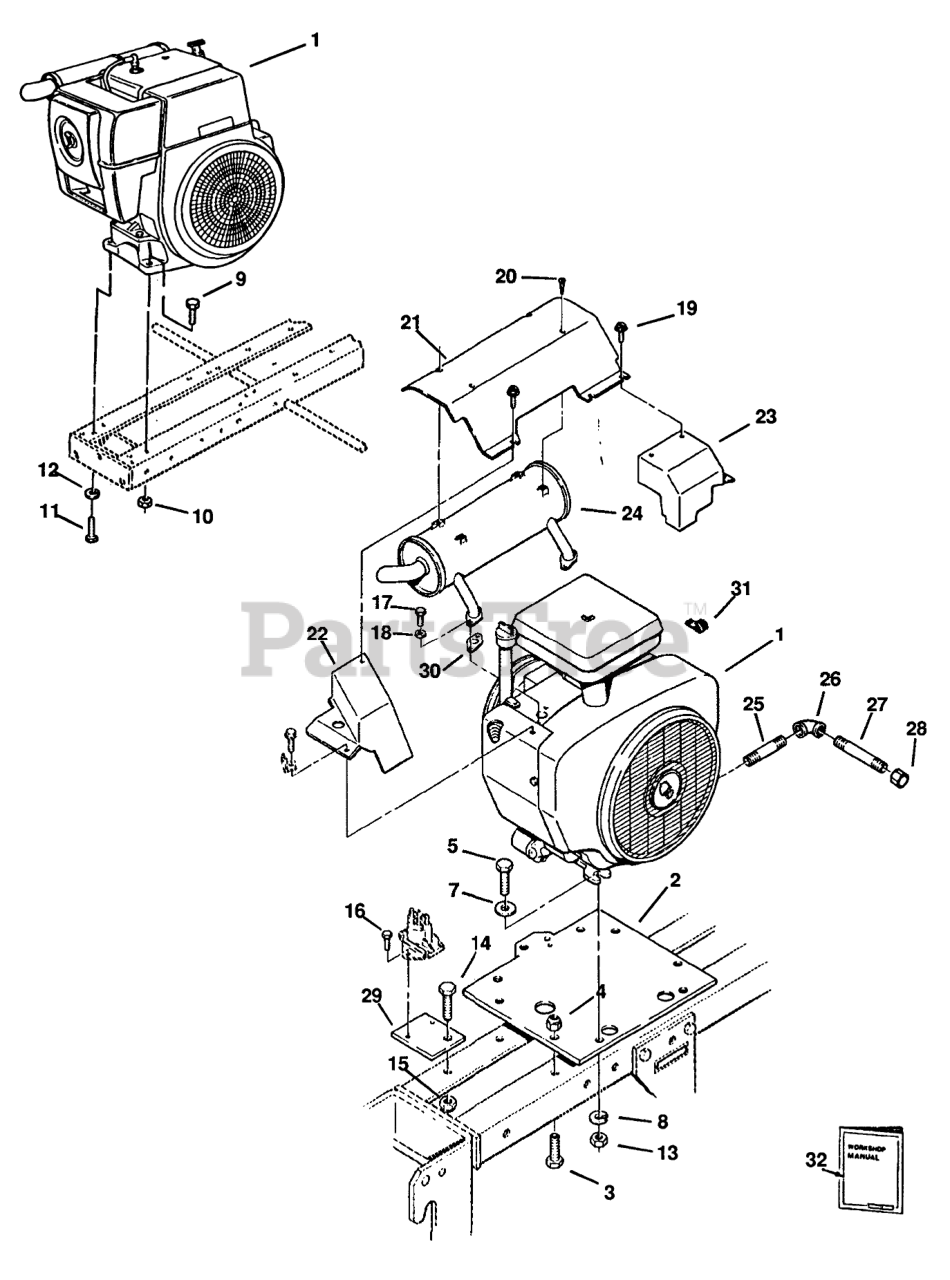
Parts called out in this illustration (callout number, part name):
1	Engine 10HP Kohler M-10-S Spec 461521310
1	Engine 12HP Kohler M-12-S Spec 471527312
1	Engine 14HP Kohler M-14-S Spec 601540414
1	Engine 16HP Onan P216G-I/10779B
2	Engine Plate
3	Bolt
4	E.S. Nut 3/8-16
5	Bolt
7	Washer
8	LOCKWASHER
9	BOLT
10	NUT
11	BOLT
12	LOCKWASHER
13	Nut
14	BOLT
15	NUT
16	S.T. Bolt 1/4-20 x 1/2
17	Bolt
18	Lockwasher
19	Bolt
20	Screw
21	Air Deflector
22	LH Exhaust Cover
23	RH Exhaust Cover
24	Muffler
25	Pipe
26	ELBOW 3/8 90 DEG
27	PIPE-NIPPLE 3/8 X 4"
28	Cap
29	PLATE-RELAY MOUNT B
30	Exhaust Gasket
31	CLIP
32	Magnum Kohler Service & Repair Manual
32	Onan Performer Twin Cylinder Service Manual
